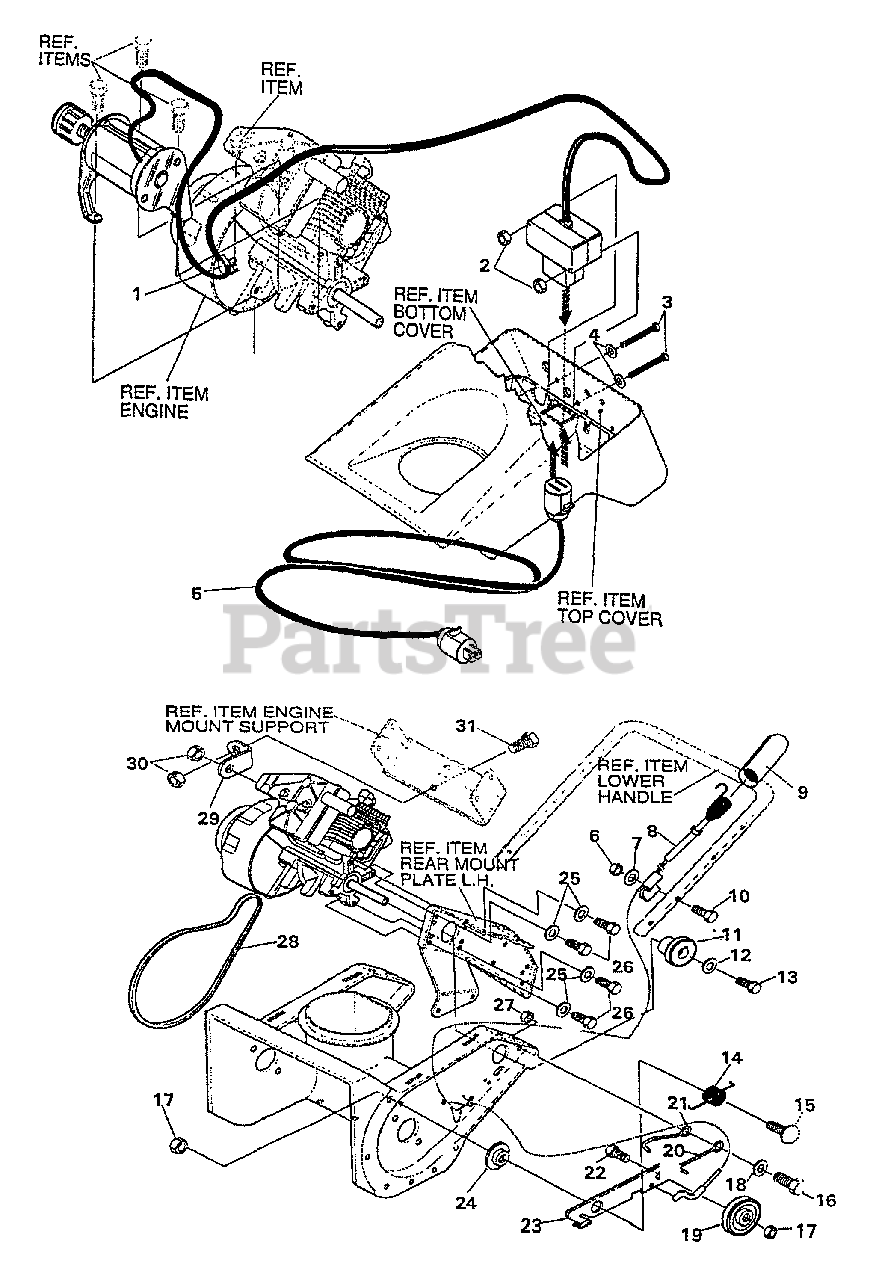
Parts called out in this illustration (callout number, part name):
1	RETAINER, WIRE
2	NUT - 8-32 -- KEPS
3	SCREW - 8-32×3.00"
4	WASHER - 0.188×0.38×0.040"
5	CORD, EXTENSION 10 FEET
6	NUT, 1/4"-20
7	WASHER
8	CABLE, DRIVE CONTROL
10	SCREW
11	PULLEY HALF, 3L, 2.00
12	WASHER
13	SCREW - 5/16-24×0.88
14	SPRING
15	BOLT, IDLER ARM
16	SCREW
17	LOCKNUT - 3/8-16
18	WASHER
19	IDLER PULLEY, 1.88×0.5×0.38
20	GUIDE, BELT 0.381DX3.30 OFF
21	GUIDE, BELT 0.381DX2.66
22	BOLT 3/8"-16×1.25 SPCARR
23	BRACKET, IDLER ARM
24	SPACER
25	WASHER
26	SCREW 5/16"-18×0.75
27	NUT, 3/8"-16
28	BELT, V3LX35, 0.048 D
29	SUPPORT, ENGINE
30	NUT, 5/16"-18
31	SCREW - 5/16-18 X0.50" -- HEX HEAD CAP
